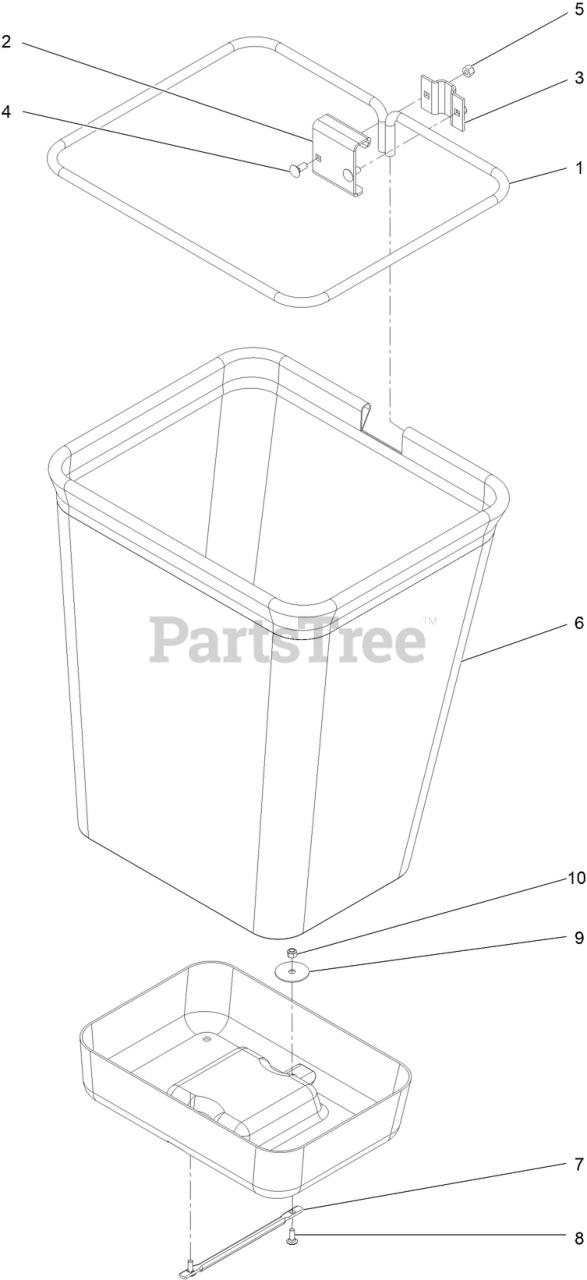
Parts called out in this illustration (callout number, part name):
1	Frame - Bag
2	Hanger-Bag
4	BOLT-CARR
5	NUT-LOCK, NI
6	Bag ASM
7	Handle-Bag
8	BOLT-CARR
10	NUT-LOCK, NI
